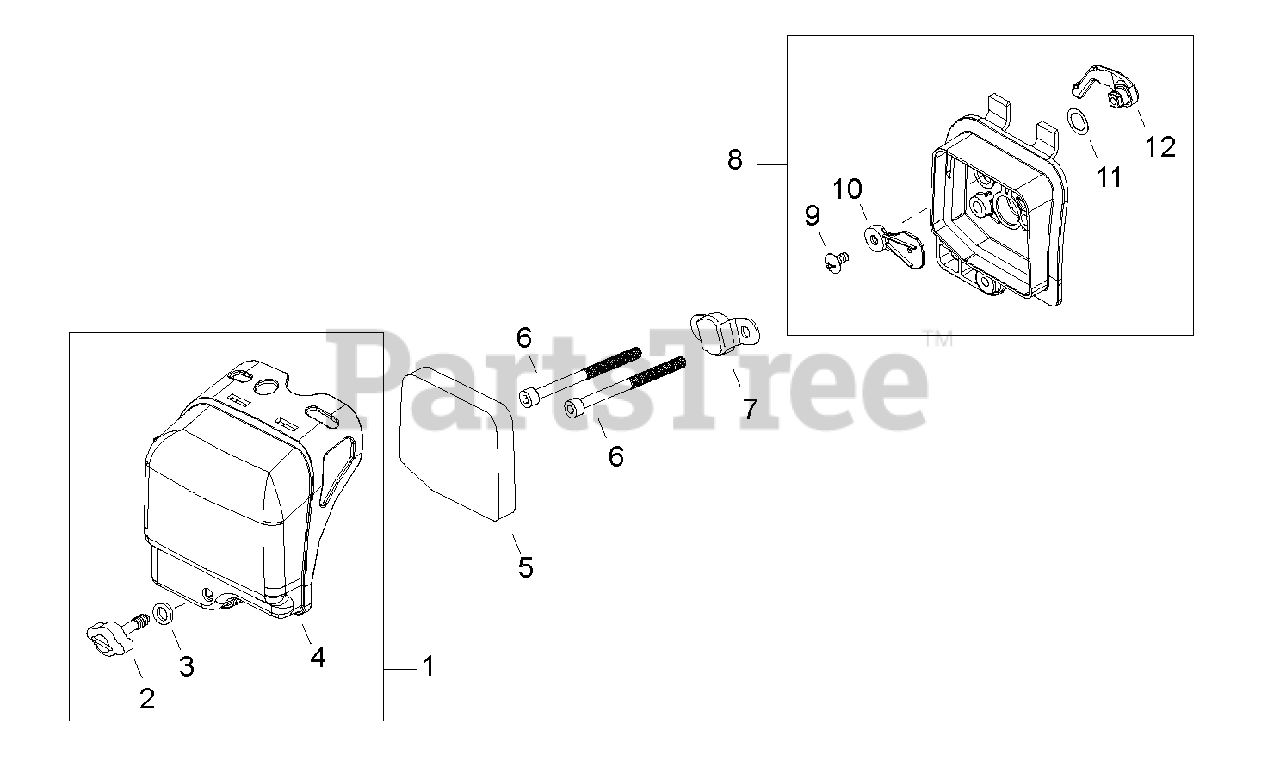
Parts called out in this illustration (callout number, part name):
1	AIR FILTER COVER ASSY
2	THUMBSCREW
3	WASHER - VYNYL
4	COVER, AIR FILTER
5	FILTER, AIR
6	SCREW - 5X60
7	PLATE, PREVENT
8	CASE, AIR FILTER
9	SCREW - 4X12
10	PLATE, CHOKE
11	WASHER - SPRING
12	LEVER, CHOKE
